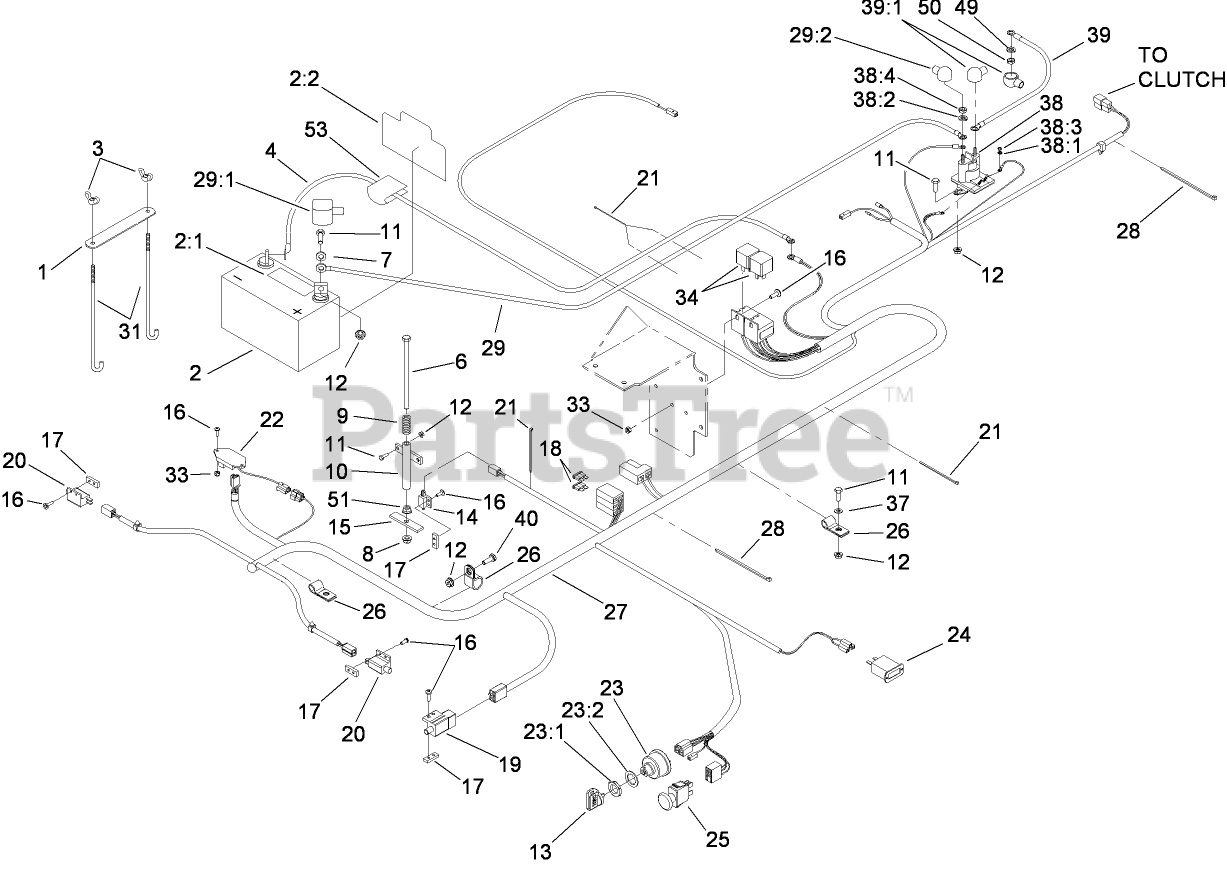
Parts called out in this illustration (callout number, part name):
1	STRAP-HOLDDOWN, BATTERY
2	BATTERY
2:1	Decal-Battery
2:2	Decal-Battery
3	WINGNUT
4	WIRE-GROUND
6	SCREW-HH
7	WASHER-FLAT
8	NUT-LOCK, NI
9	SPRING-SWITCH, SEAT
10	MOUNT-SPRING, SEAT
11	SCREW-HH
12	NUT-HF
13	KEY-IGNITION
14	SWITCH-CLOSED, NORMALLY
15	PLATE-SWITCH, SEAT
16	SCREW-PPH
17	PLATE-TAPPED
18	FUSE-BLADE TYPE, 20 AMP
19	SWITCH
20	SWITCH-OPEN, NORMALLY
21	TIE-CABLE
22	MODULE-DELAY, SEAT
23	SWITCH ASM
23:1	NUT-HH
23:2	WASHER-TOOTH, INTERNAL
24	METER-HOUR
25	SWITCH-PTO
26	CLIP-LOOM
27	Harness-Wire
28	TIE-PLASTIC
29	POSITIVE BATTERY CABLE ASM
29:1	INSULATOR-BATTERY
29:2	INSULATOR-SOLENOID
31	BOLT-HOLDDOWN
33	NUT-LOCK, NI
37	WASHER-FLAT
38	SWITCH-SOLENOID
38:1	WASHER-LOCK
38:2	WASHER-LOCK
38:3	NUT-HEX
38:4	NUT-JAM
39	POSITIVE STARTER CABLE ASM
39:1	INSULATOR-SOLENOID
40	SCREW-HH
49	WASHER-LOCK
50	NUT-HEX
51	NUT-HEX
53	DECAL-INSTRUCTIONS, CHARGING
